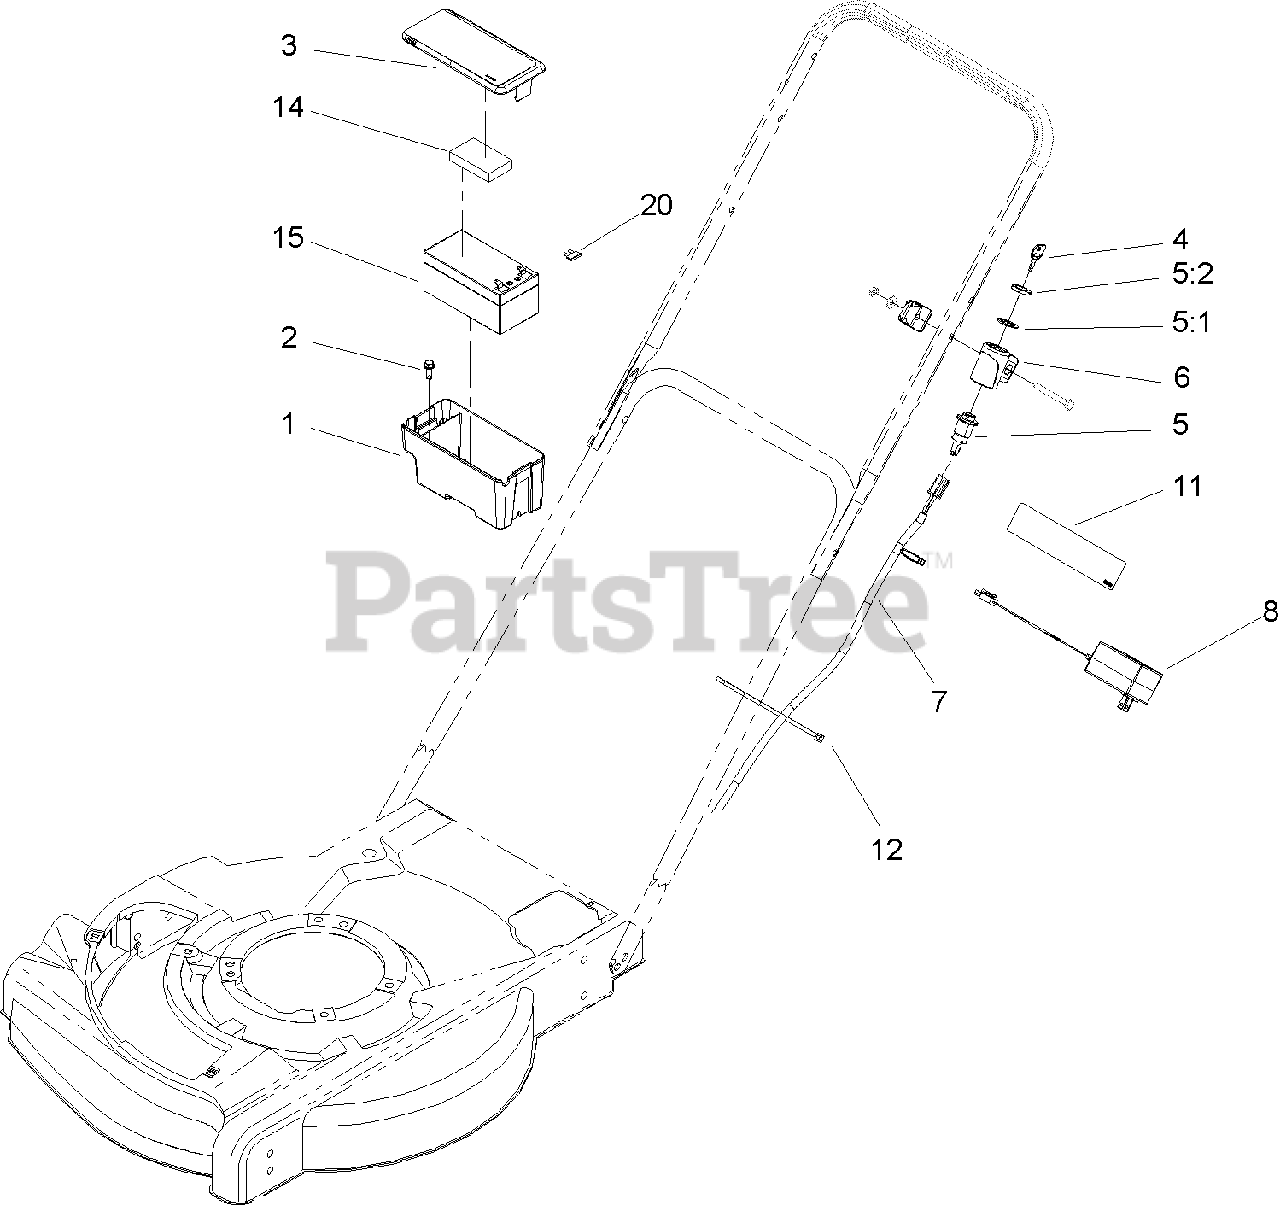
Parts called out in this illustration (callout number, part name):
1	Box-Battery
2	SCREW-TEK
3	Cover-Battery
3	COVER-BATTERY
4	KEY-IGNITION
5	SWITCH-STARTER
5:1	WASHER-TOOTH
6	Mount-Switch
7	HARNESS-WIRE
12	STRAP-TIE
14	Foam-Battery
14	FOAM-BATTERY, TOP
15	BATTERY-12 VOLT
20	FUSE-40 AMP
